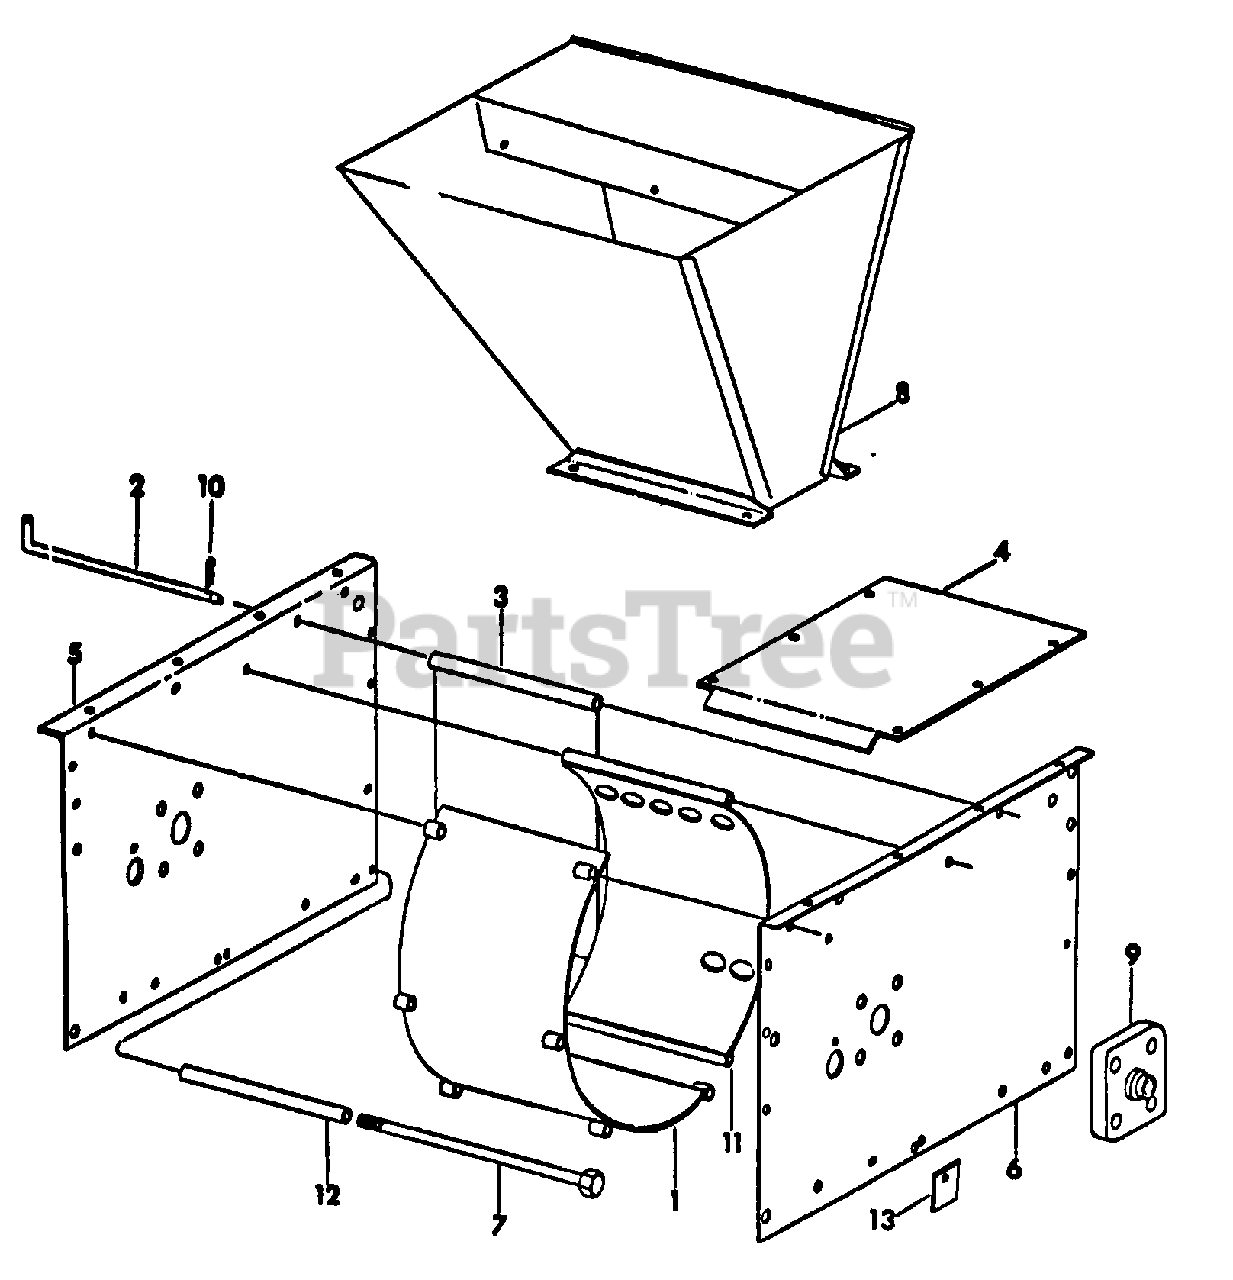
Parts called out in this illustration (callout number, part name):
2	Rod, Screen & Baffle
3	Plate, Baffle
4	Plate, Top
5	Plate, Side LH
6	Plate, Side RH
9	Bearing, Flange
10	Pin, Quick Attachable
11	Screen, 1 In. Perforations
13	Plate, Cover
